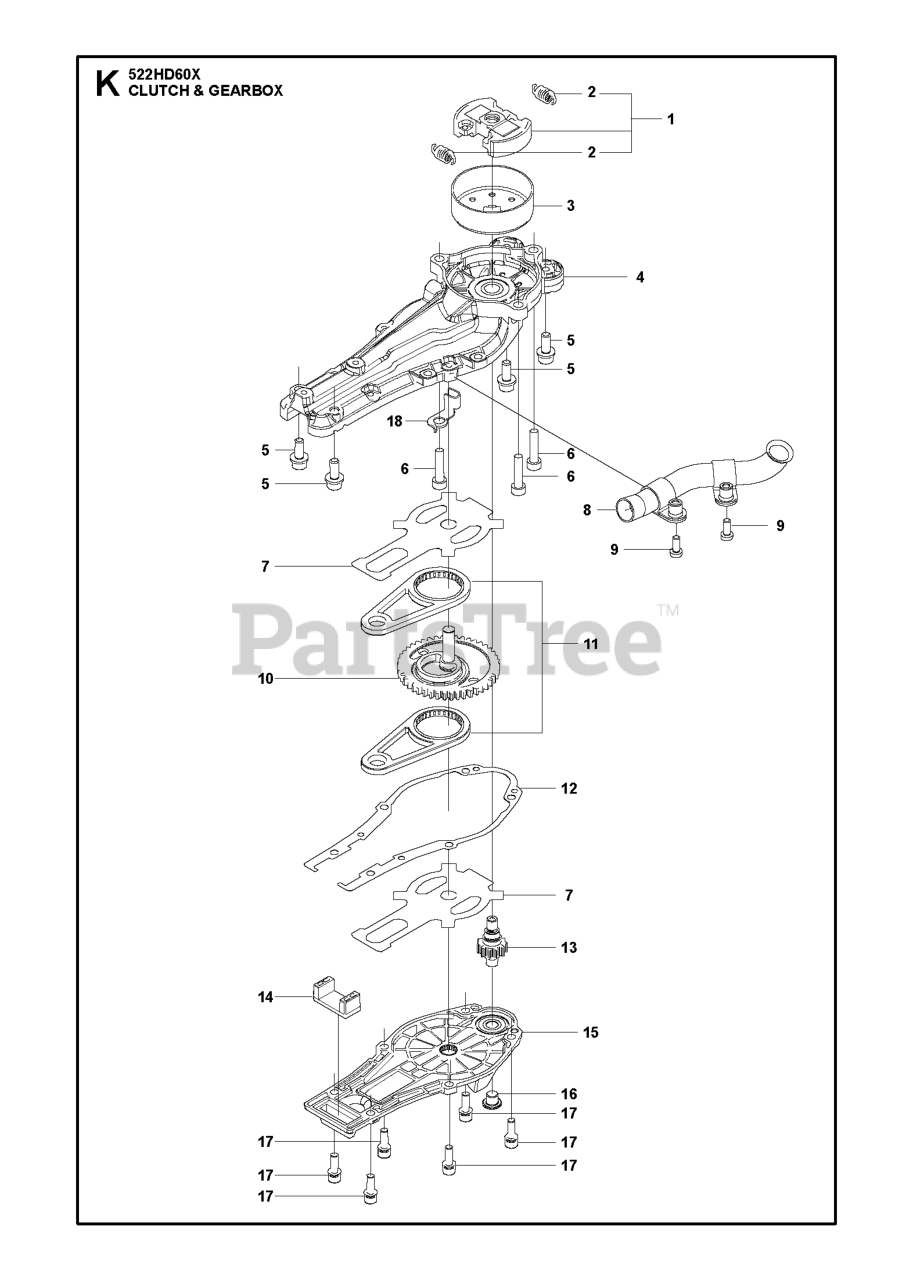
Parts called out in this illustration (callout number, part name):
1	CLUTCH ASSY
2	CLUTCH SPRING CLUTCH SPRING
3	CLUTCH DRUM COPPER BRAZING
4	GEAR HOUSING ASSY KIT UPPER
7	PLATE THRUST
8	EXHAUST PIPE ASSY FOR A051 PRO
10	GEAR WHEEL ASSY
12	GASKET GEAR HOUSING
13	GEAR DRIVE
14	SEALING PLASTIC
15	GEAR HOUSING ASSY KIT LOWER
16	SCREW PLUG HEXALOBULAR SOCKET
